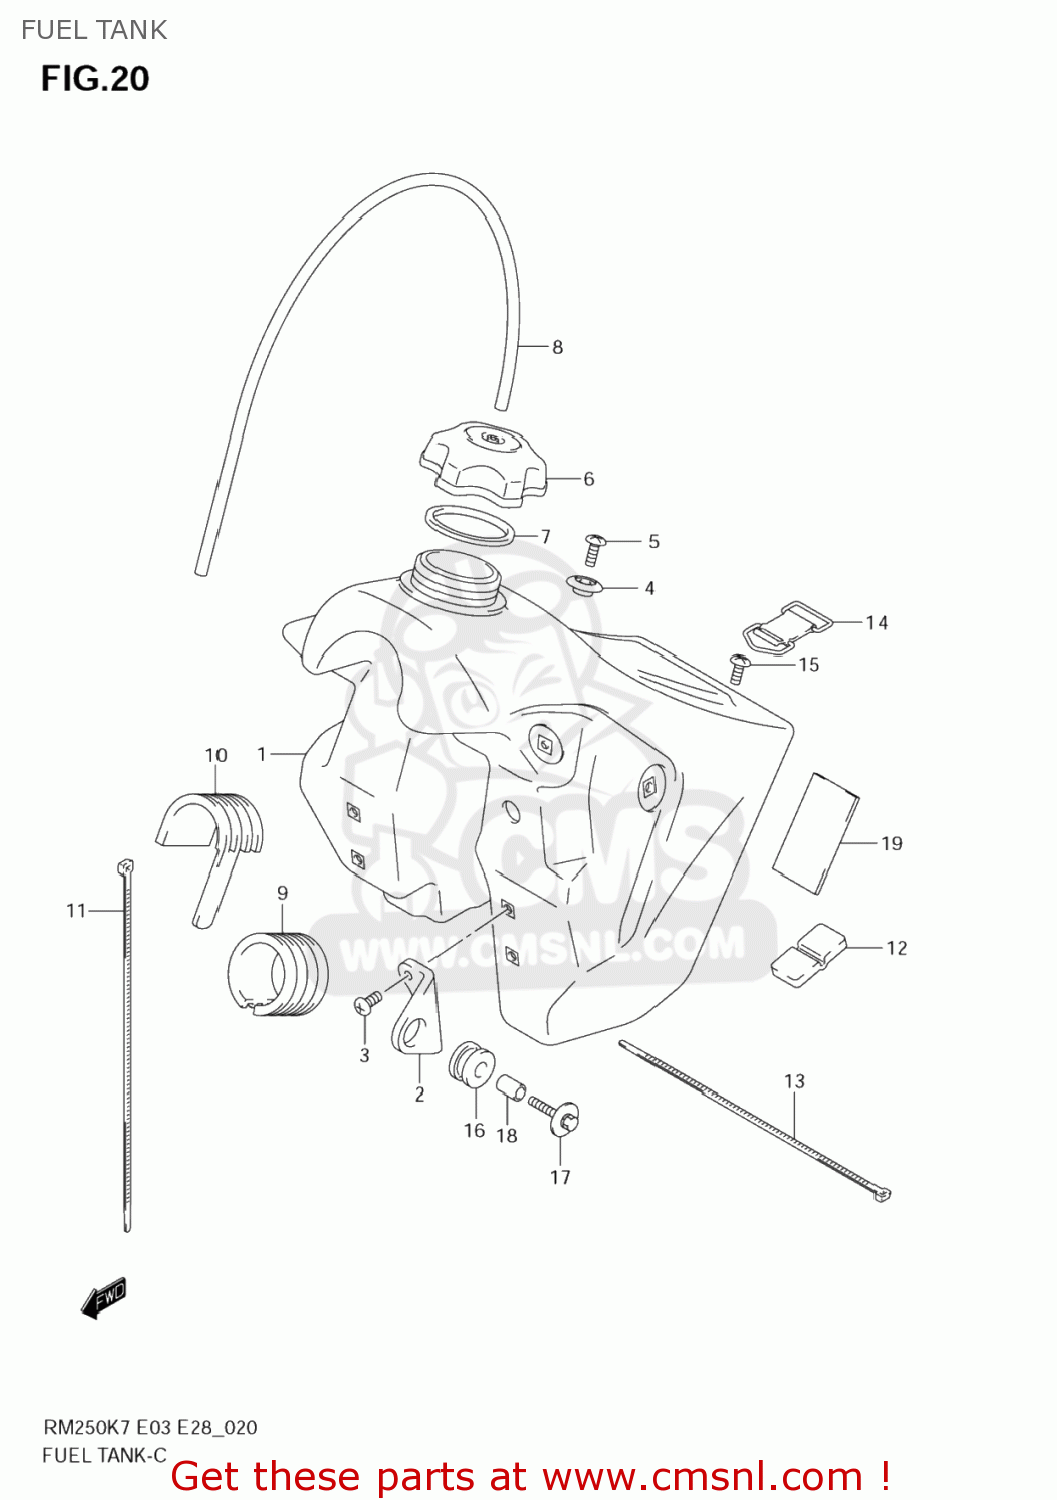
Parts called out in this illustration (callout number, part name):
1	TANK,FUEL(YELLOW)
2	BRACKET,FUEL TANK FR
3	BOLT(6X12)
4	HOOK,SEAT FR
5	SCREW
6	CAP,FUEL TANK FILLER
7	GASKET,CAP (NAS)
8	HOSE(5X8.2X600)
9	CUSHION,FUEL TANK NO.1
10	CUSHION,FUEL TANK
11	CLAMP(L:300)
12	CUSHION,FUEL TANK RR
13	CLAMP(L:250)
14	BAND,FUEL TANK RR
15	SCREW(6X13.5)
16	CUSHION,MUFFLER
17	BOLT(6X35)
18	SPACER(6.5X9X13.5)
19	PROTECTOR(40X85X5)
